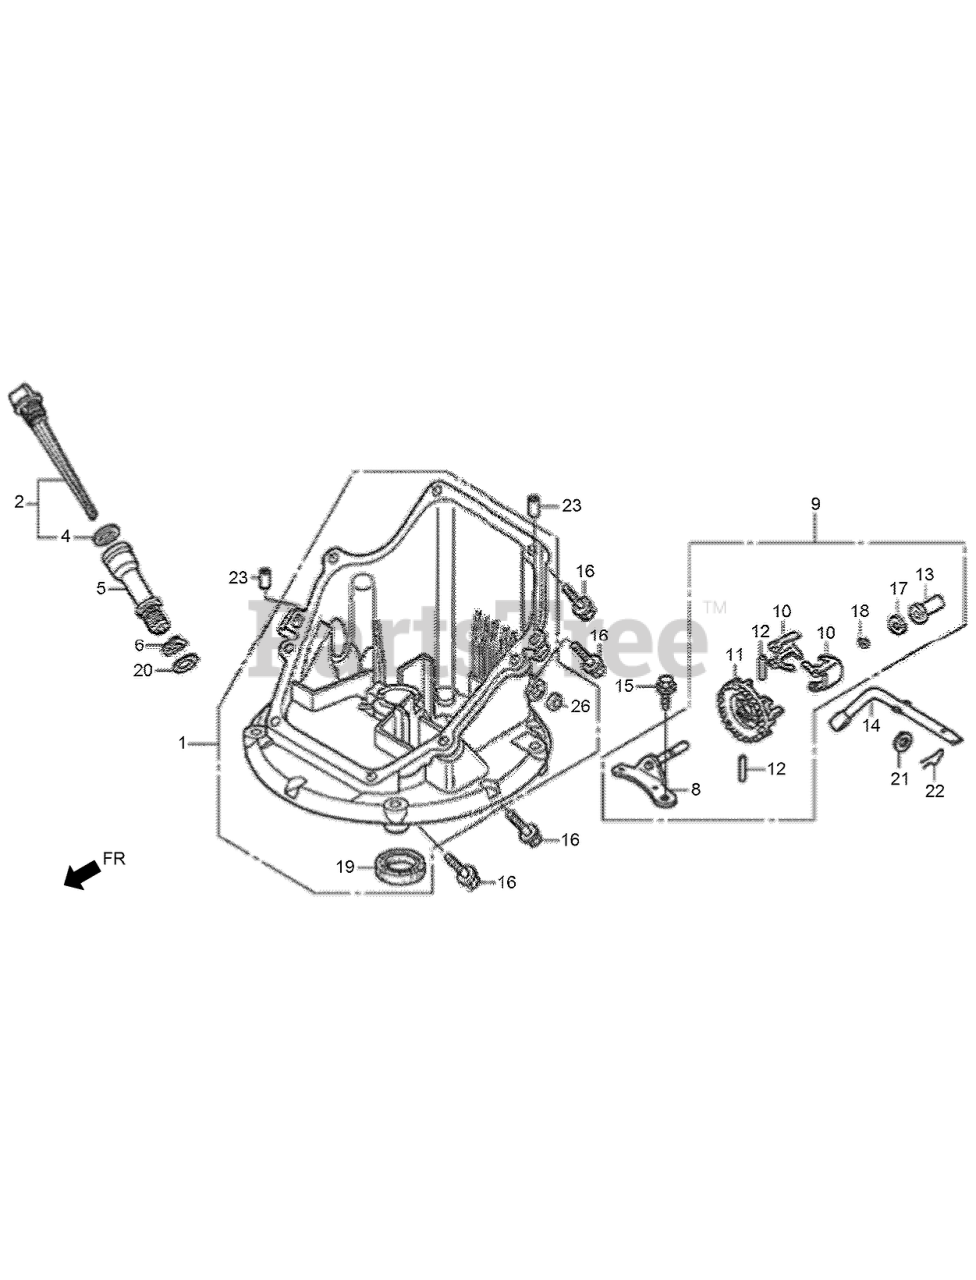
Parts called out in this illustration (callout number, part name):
1	PAN ASM-OIL
2	GAUGE ASM-OIL LEVEL
4	PACKING-OIL FILLER CAP
5	EXTENSION-OIL FILLER
6	WASHER-EXTENSION LOCK
8	GOVERNOR HOLDER SHAFT ASM
9	GOVERNOR ASM
10	WEIGHT-GOVERNOR
11	HOLDER-GOVERNOR WEIGHT
12	PIN-GOVERNOR WEIGHT
13	SLIDER-GOVERNOR
14	SHAFT-GOVERNOR ARM
15	BOLT-FLANGE-6X14
16	BOLT-FLANGE-6X26
16	BOLT-FLANGE-6X25
17	WASHER-THRUST-6MM
18	CLIP-GOVERNOR HOLDER
19	OIL SEAL-28X41.25X6
20	O-RING-14.8X2.4
21	WASHER-PLAIN-6MM
22	PIN-LOCK-8MM
23	DOWEL PIN-8X20
26	OIL SEAL-6X11X4
